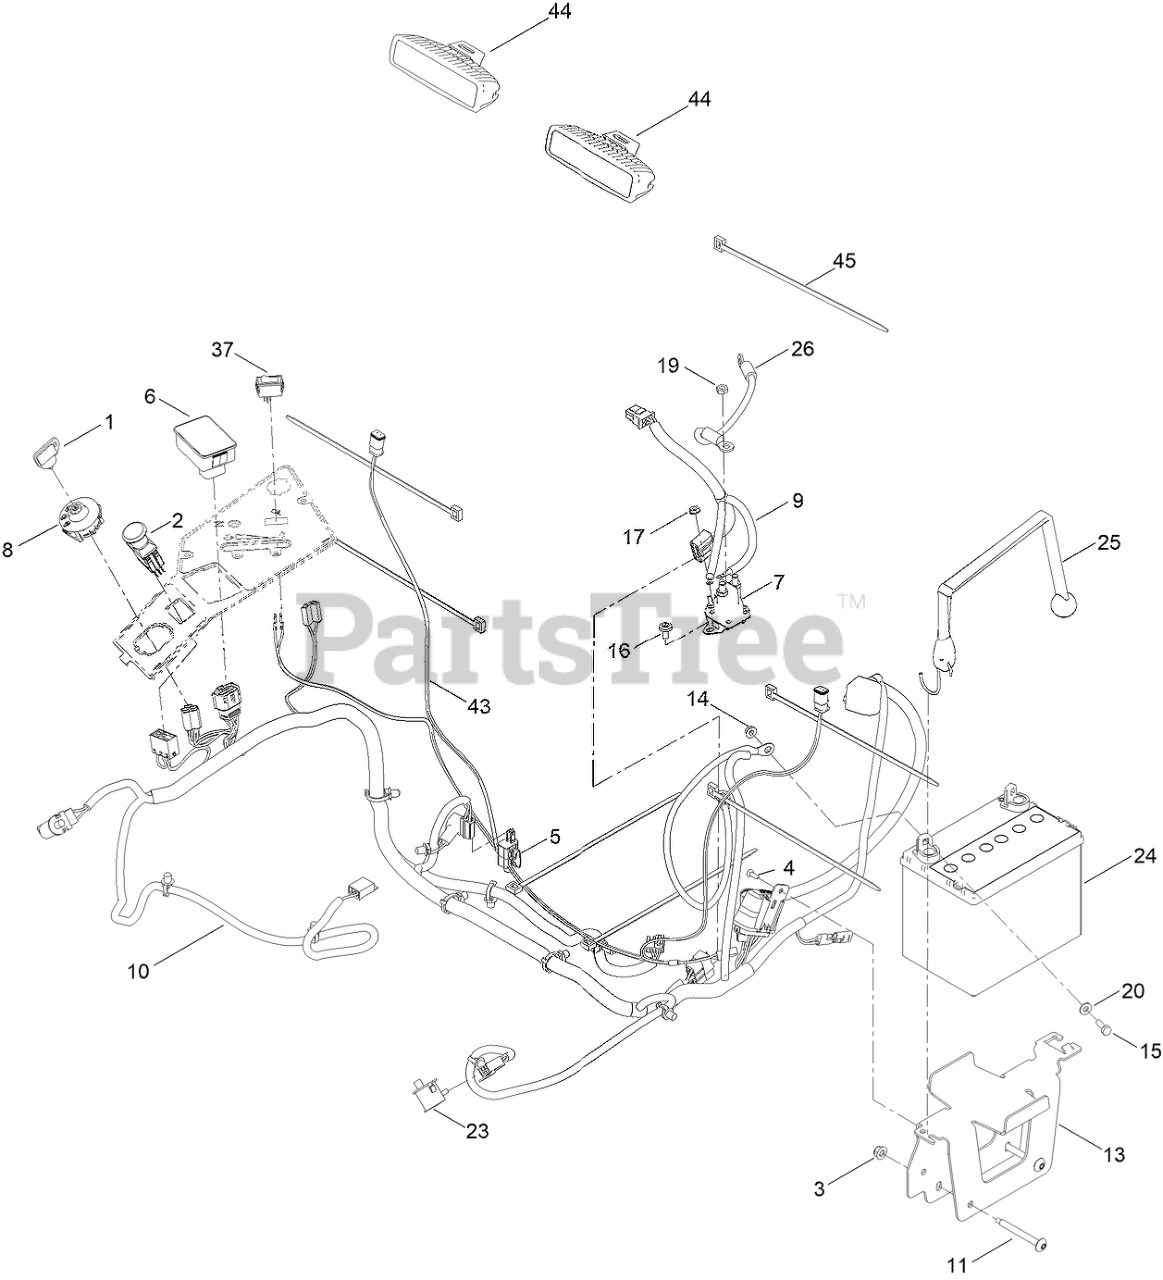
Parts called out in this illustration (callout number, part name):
1	KEY-IGNITION
2	SWITCH-PTO
3	NUT-HF, NI
4	SCREW-FORMING, THREAD
5	SWITCH
6	MODULE ASM
7	SOLENOID
8	SWITCH-IGNITION
9	ADAPTER-HARNESS, WIRE
10	HARNESS-WIRE
11	SCREW-TORX
13	TRAY-BATTERY
14	NUT-HF
15	SCREW-HH
16	SCREW-TORX
17	NUT-KEPS
19	NUT-JAM
20	WASHER-FLAT
23	SWITCH-BAIL
24	BATTERY
25	STRAP, BUNGEE
26	CABLE-BATTERY, POSITIVE
37	SWITCH-ROCKER
43	HARNESS-WIRE, LIGHT KIT
44	LIGHT-LED
45	TIE-PLASTIC
